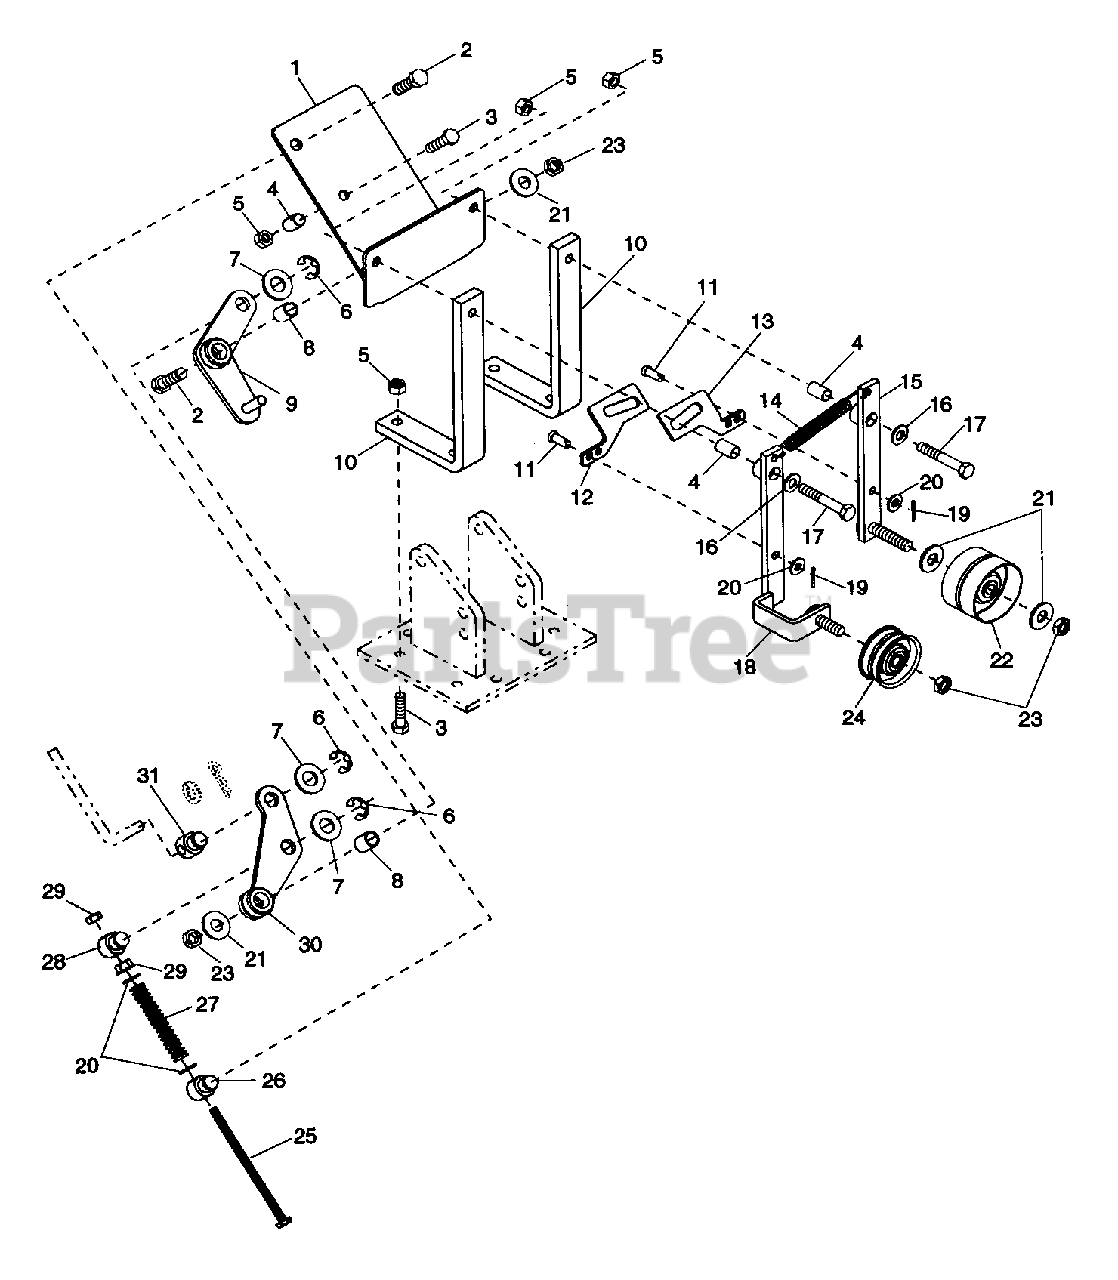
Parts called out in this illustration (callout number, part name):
1	SHIFTING PLATE
2	BLT-HEX .38-16X1.25 PL GR 2
3	BLT-HEX .31-18X1.25 PL GR2
4	SLEEVE BUSHING
5	NUT-LK .312-18 GR A PL
6	RG-RTNG-EXT .500X.042 (E)
7	WSHR-FL-STL .531X1.062X.095 PL
8	BSHG-SLV .406 X .545 X .68
9	BELLCRANK WELDMENT
10	SHIFT MTG BAR
11	CLEVIS PIN
12	SHIFT LINK - REVERSE
13	SHIFT LINK - FORWARD
14	SG-TENS .067X.437X3.25 WLD 4.5
15	IDLER ARM - FORWARD
16	WSHR-FL-STL.344X.688X.065PL
17	BLT-HEX .31-18X2.00 PL GR2
18	IDLER ARM - REVERSE
19	PIN-COTR .06X.50
20	WSHR-FL-STL.281X.62X.065 PL
21	WSHR-FL-STL .438X1.0X.083 PL
22	IDLER-FLAT 2.25 X .38
23	NUT-LK-JAM-CTR .375-16 PL
24	IDLER-FLAT 2.000X.375
25	BLT-HEX .25-20 X 4.5 PLATED
26	PIVOT - BELLCRANK
27	SG-COMP .080X.52X2.90
28	THREADED PIVOT - RODCRANK
29	NUT-HEX .250-20 PL
30	RODCRANK WELDMENT
31	PIVOT - SHIFT LEVER ROD
